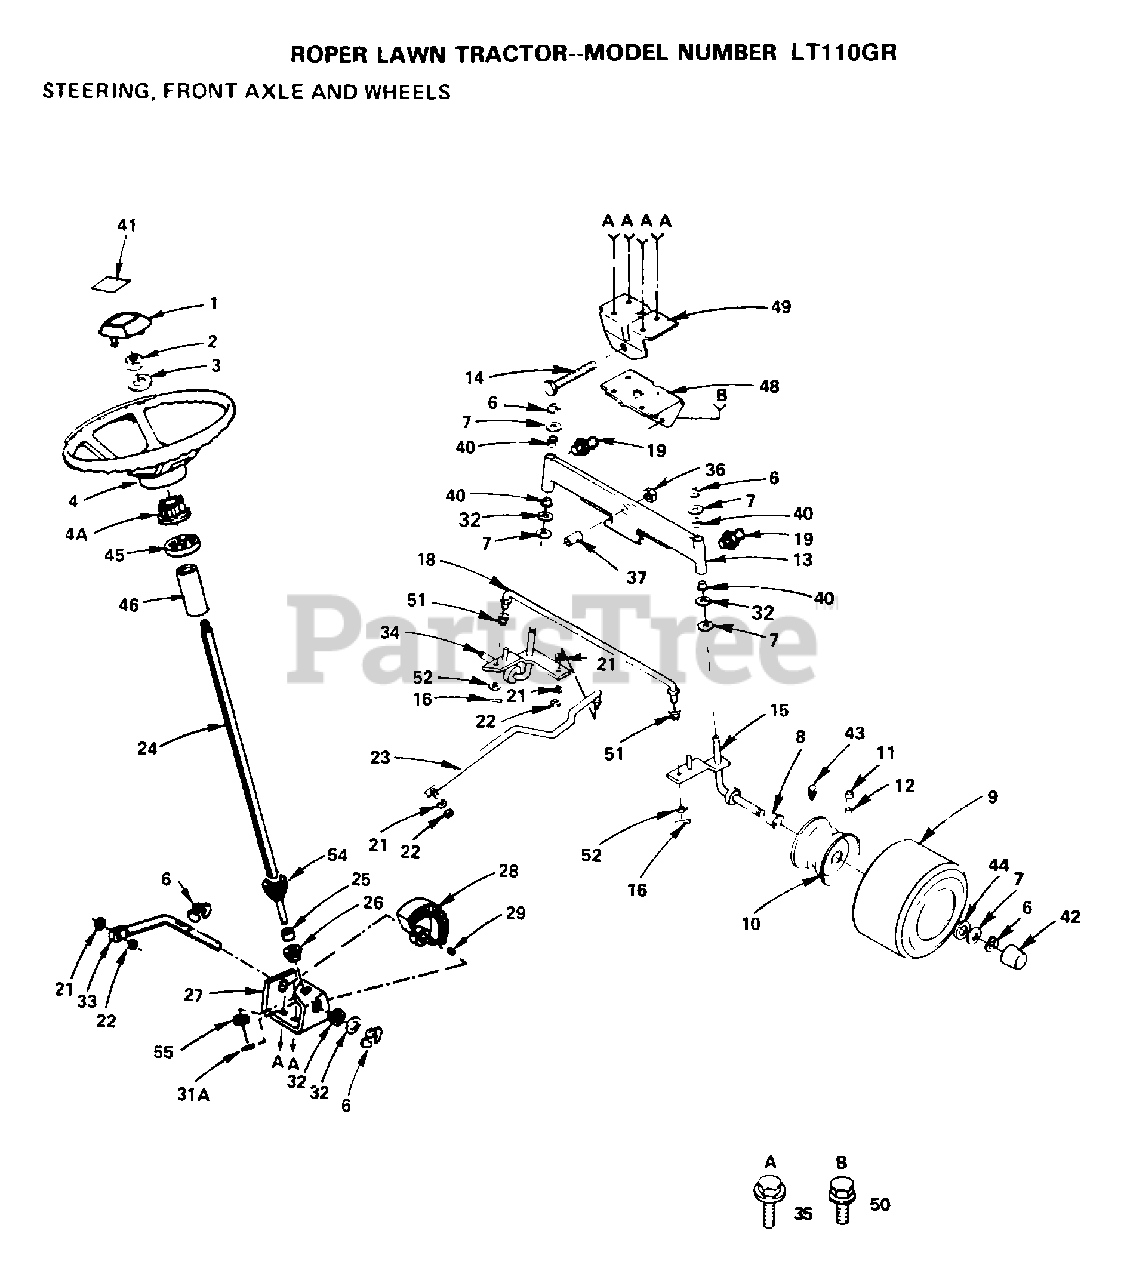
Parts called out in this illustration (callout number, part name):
1	INSERT-WHEEL LT
3	WASHER
4A	ADAPTER LT
5	NYLINER T
6	RING
8	"FLANGE, BEARING"
11	VALVE STEM LT
12	VALVE CAP
13	FRONT AXLE
14	BOLT LT
16	COTTER PIN
19	ZERK M
20	BEARING
21	LOCKWASHER
23	LINK-DRAG LT
25	SHAFT SPACER LT
26	BUSHING
28	GEAR.SECTOR.HYT
29	KEY-WOODRUFF LT
30	WASHER D
32	WASHER .T
33	ROD STEERING T
34	SPINDLE-LH LT
35	SCREW
36	"NUT-LOC,FLANGE LT"
40	COL. SRTG. BEAR.
41	DECAL - STEERING WHEEL
42	HUB CAP
43	FITTING LT
48	SUPPORT.SADDLE.FT
49	SUPPORT-SADDL T
50	SCREW LT
52	WASHER
54	GEAR PINION T
56	WASHER
